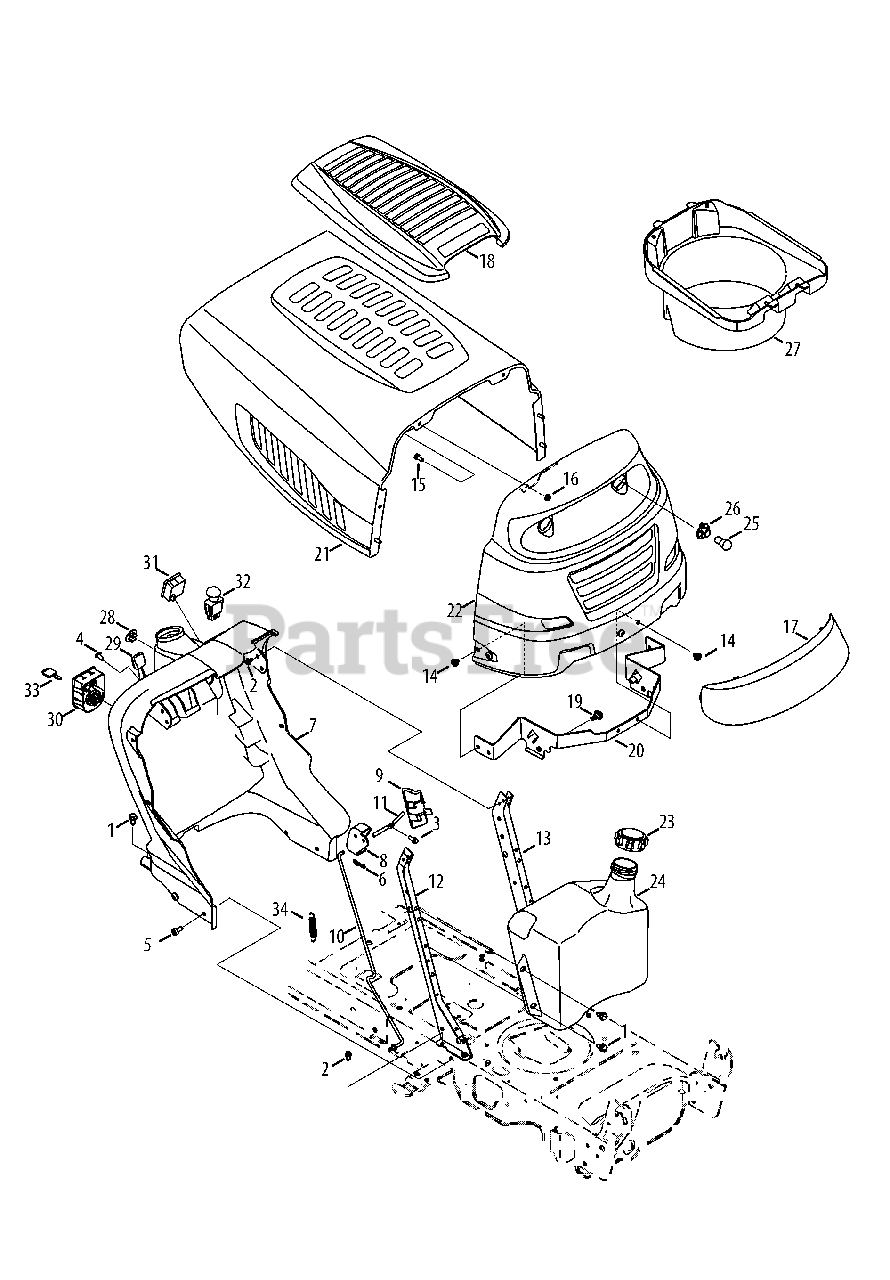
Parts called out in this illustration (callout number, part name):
1	Taptite Screw ,5/16-18:.750
2	Taptite Screw ,1/4-20:0.500
3	Hi-Lo Screw, 1/4-15:0.750
4	Screw, 1/4-14:0.625
5	Taptite Screw ,5/16-18:0.750
6	Bow Tie Cotter Pin
7	Dash Panel
8	Dash Lever
9	Cruise Cover
10	Control Rod
11	Lever
12	RH Support Plate
13	LH Support Plate
14	Taptite Screw ,5/16-18:0.375
15	Hex Screw, 1/4-20:.620
16	Flangelock Nut, 1/4-20
17	Grill Lens
18	Hood Scoop
19	Shoulder Screw, .43X.29:5/16-18
20	Hood Pivot Bracket
22	Grill
23	Fuel Cap
24	Fuel Tank
26	Lamp Socket
28	Choke Plug
29	Throttle/Choke Cable
30	Key Switch Module
31	Hour Meter
32	Electric PTO Switch
33	Key, Assembly
34	Extension Spring, .500 DIA x 2.733 LG
